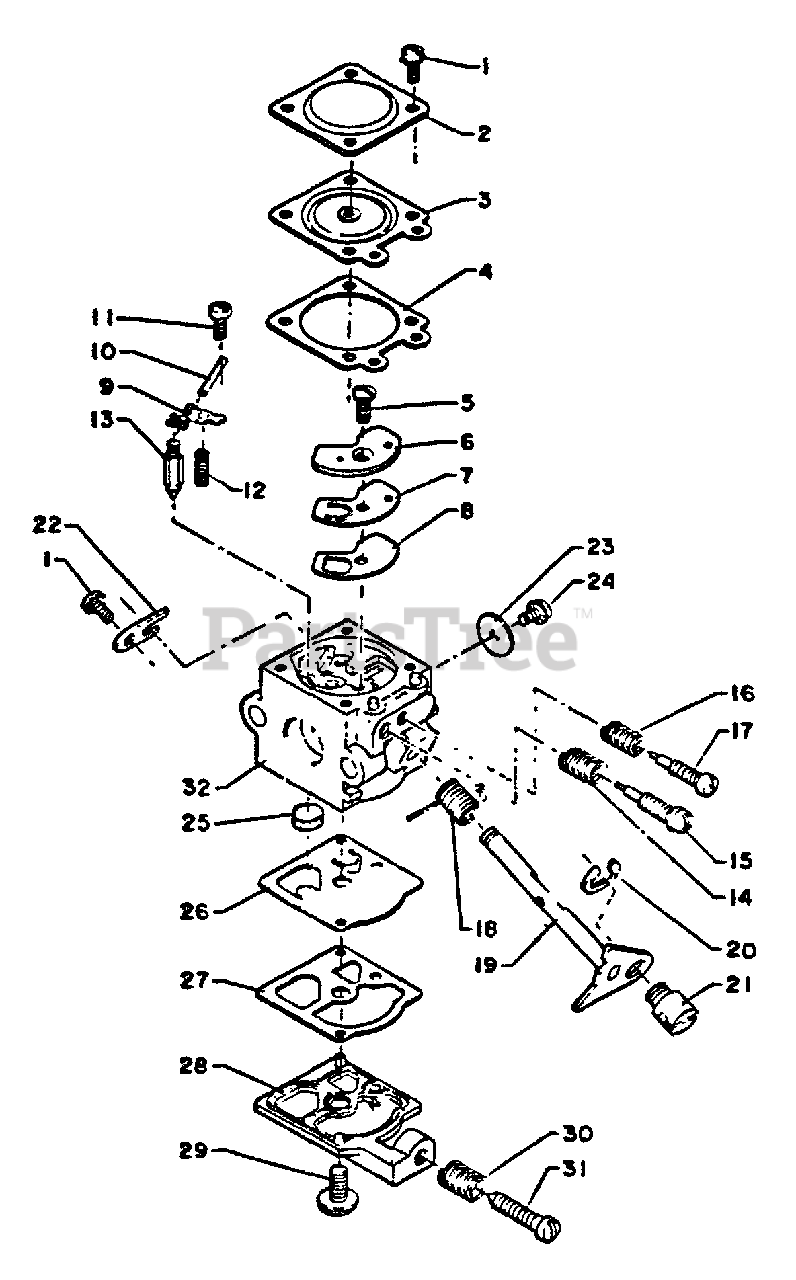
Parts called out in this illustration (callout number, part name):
1	SCREW
2	COVER, METERING
3	DIAPHRAGM, METERING
4	GASKET, METERING
5	SCREW, CIRCUIT PLATE
6	PLATE, CIRCUIT
7	DIAPHRAGM, CIRCUIT PLATE
8	GASKET, CIRCUIT PLATE
9	LEVER, METERING
10	PIN, METERING LEVER
11	SCREW, METERING LEVER PIN
12	SPRING, METERING LEVER
13	VALVE, INLET NEEDLE
14	SPRING, HIGH SPEED NEEDLE
15	NEEDLE - HIGH SPEED
15	SPRING, IDLE ADJUST
15	NEEDLE - LOW SPEED
18	SPRING, THROTTLE RETURN
19	SHAFT, THROTTLE
20	RING, RETAINING
22	CLIP, THROTTLE SHAFT
23	VALVE, THROTTLE
25	STRAINER
26	DIAPHRAGM, PURGE
27	GASKET, PURGE
28	COVER, PUMP
29	SCREW, PUMP COVER
30	SPRING, IDLE ADJUST
31	SCREW, IDLE ADJUST
32	BODY, CARBURETOR
